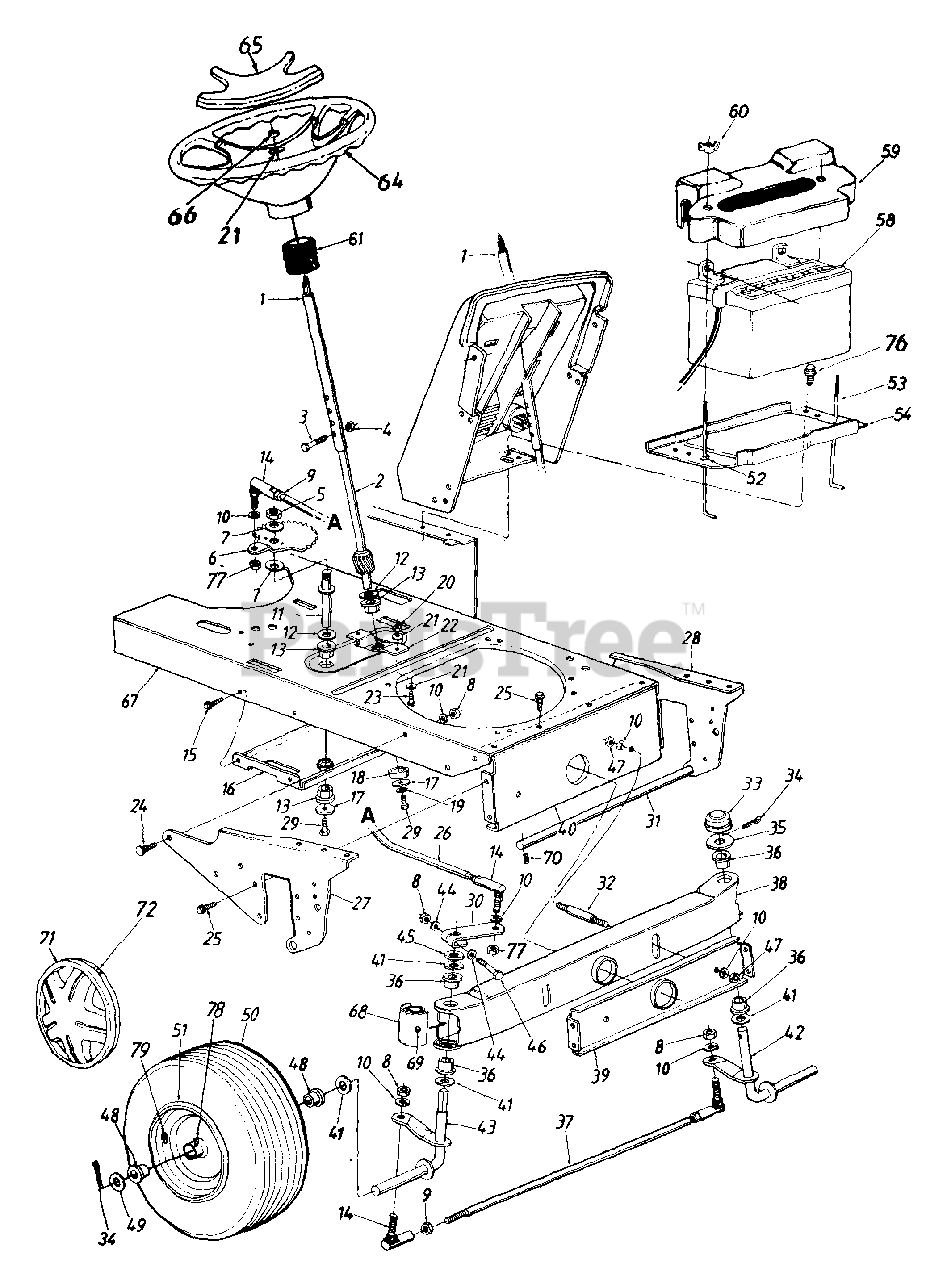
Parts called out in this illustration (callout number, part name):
1	Steering Column Ass'y.
2	Lower Steering Shaft
3	Hex Bolt 1/4-20 x 1.31" Lg.
4	Hex L-Nut 1/4-20 Thd.
5	Hex Nut 5/8-18 Thd.
6	Steering Gear Segment
7	Bell-Wash. 5/8" I.D. x 1.25" O.D.
8	Hex Nut 3/8-24 Thd.
9	Hex Jam Nut 3/8-24 Thd.
10	L-Wash. 3/8" I.D.
11	Steering Gear Segment Shaft
12	Fl-Wash. .64" I.D. x 1.24" O.D.
13	Hex Flange Brg. .63" I.D.
14	Ball Joint Ass'y.
15	Hex Wash. Hd. TT-Tap Scr. 1/4-20 x .5" Lg.
16	Deck Idler Support Brkt.
17	Fl-Wash. .33" I.D. x 1.25" O.D.
18	Spacer .985" I.D. x 1.25" O.D.
19	L-Wash. 5/16" I.D.
20	Hex Nut 5/16-24 Thd.
21	Bell-Wash. .345" I.D. x .88" O.D.
24	Ribbed Neck Bolt 3/8-24 x .8" Lg.
25	Hex Wash. TT-Tap Scr. 5/16-18 x .62" Lg.
26	Steering Drag Link
27	Pivot Bar Side Plate - R.H.
28	Pivot Bar Side Plate - L.H.
29	Hex Bolt 5/16-18 x .62" Lg.
30	Steering Arm
31	Deck Connecting Rod
32	Pivot Bar Shld. Bolt 3/8-16 x 5/8" Lg.
33	Cap
34	Cotter Pin 5/32" Dia.
36	Flange Brg. .757" I.D.
37	Tie Rod 20.25" Lg.
38	Pivot Bar Assy.
41	Fl-Wash. .76" I.D. x 1.49" O.D.
42	Front Axle Ass'y. - L.H.
43	Front Axle Ass'y. - R.H.
44	Bowed Washer
45	Spacer .755" I.D. x 1.25" O.D.
46	Hex Bolt 3/8-24 x 2.25" Lg.
47	Hex Nut 3/8-16 Thd.
48	Ball Brg. .75" I.D.
49	Fl-Wash. .71" I.D. x 1.5" O.D.
51	Rim Only
52	Push Nut
53	Battery Hold Down Rod
54	Battery Plate
58	Battery
59	Battery Cover
60	Wing Nut Plastic 1/4-20 Thd.
61	Steering Bellow
64	Steering Wheel
65	Steering Wheel Insert
66	Hex L-Nut 5/16-24 Thd.
69	Grease Fitting
70	Internal Cotter Pin
71	Hub Cap
72	Spring Clip
76	Hex AB-Tap Scr. 1/4 x .62" Lg.
77	Hex Jam L-Nut 3/8-24 Thd.
78	Grease Fitting
79	Air Valve
